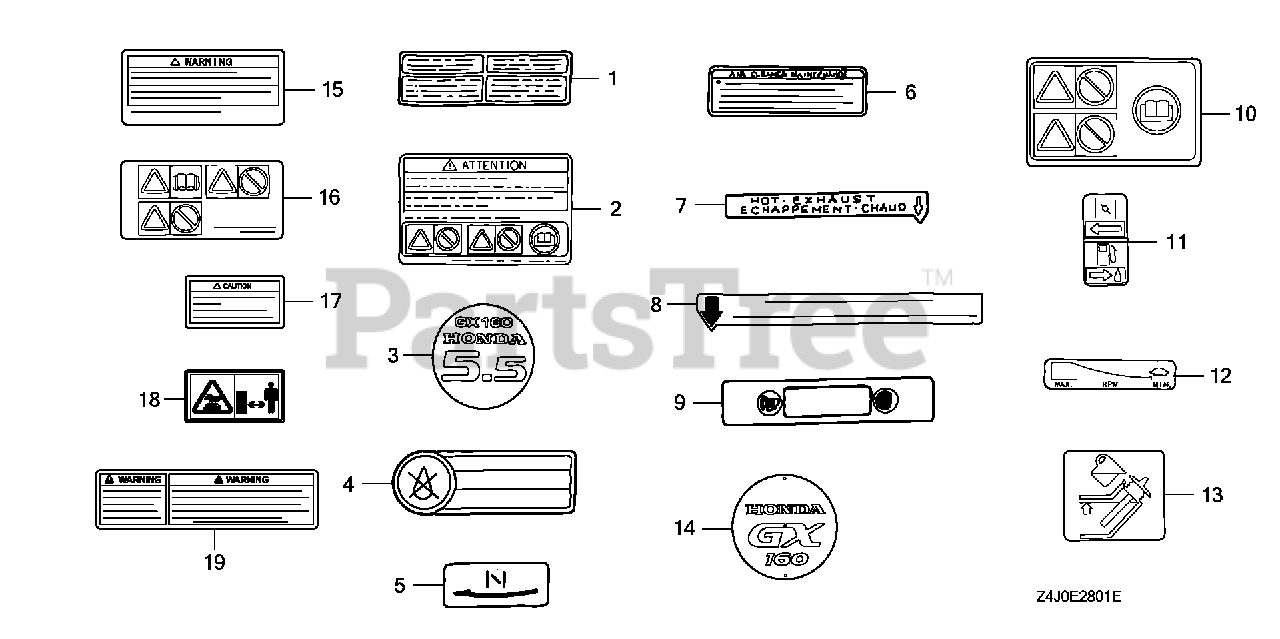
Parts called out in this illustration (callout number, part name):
15	MARK, OPERATOR CAUTION (FRENCH)(MADE IN JAPAN)
16	MARK, OPERATOR CAUTION (PICTOGRAPH)
17	MARK, EX. CAUTION (FRENCH)
18	MARK, EX. CAUTION (PICTOGRAPH)
19	LABEL, SPARK WARNING
